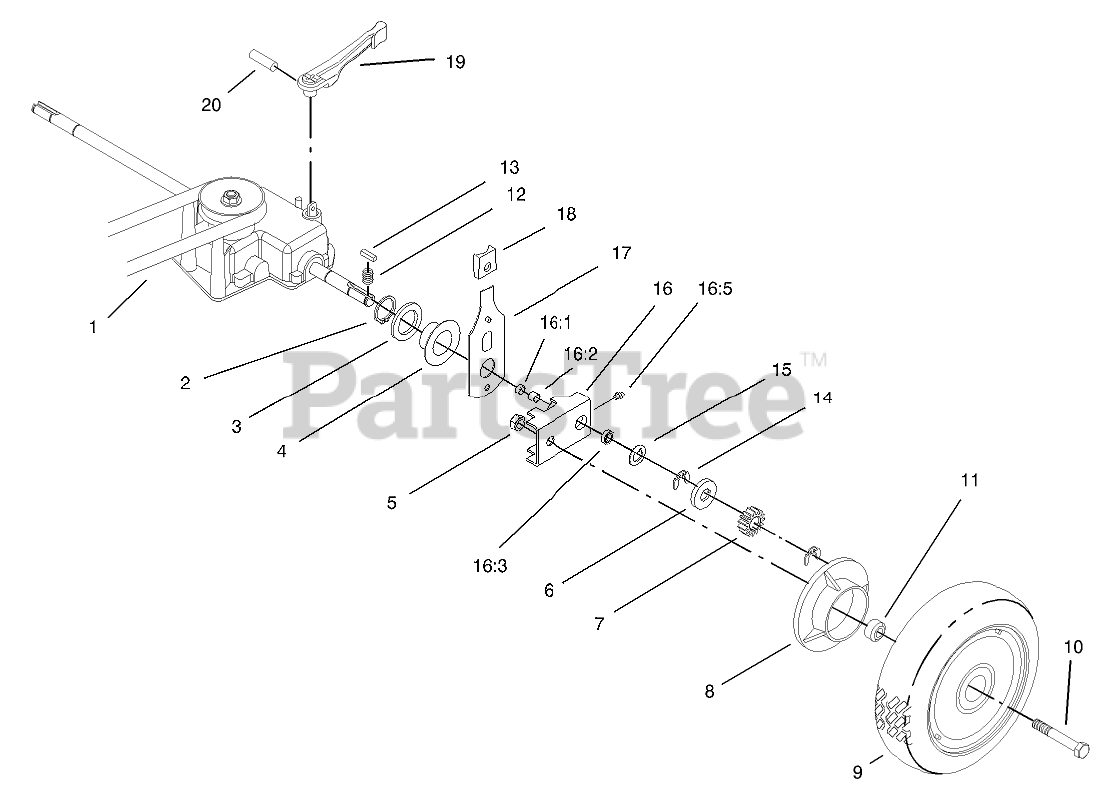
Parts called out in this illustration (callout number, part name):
1	V-BELT
2	RING-RETAINING
3	WASHER
4	CAP-END
5	NUT-LOCK, CONE
6	WASHER-THRUST, OUTER
7	GEAR-PINION
8	COVER-WHEEL
9	Wheel And Tire ASM
10	SCREW-HH
11	SPACER-COVER, WHEEL
12	SPRING-COMPRESSION
14	RING-RETAINING
15	WASHER-THRUST, OUTER
16	PIVOT ARM ASM
16:1	SEAL-OIL
16:2	BEARING-ROLLER
16:3	BEARING-WHEEL
17	REAR SPRING ARM ASM
18	KNOB-ARM
19	LEVER-SHIFT
20	PIN-COIL
